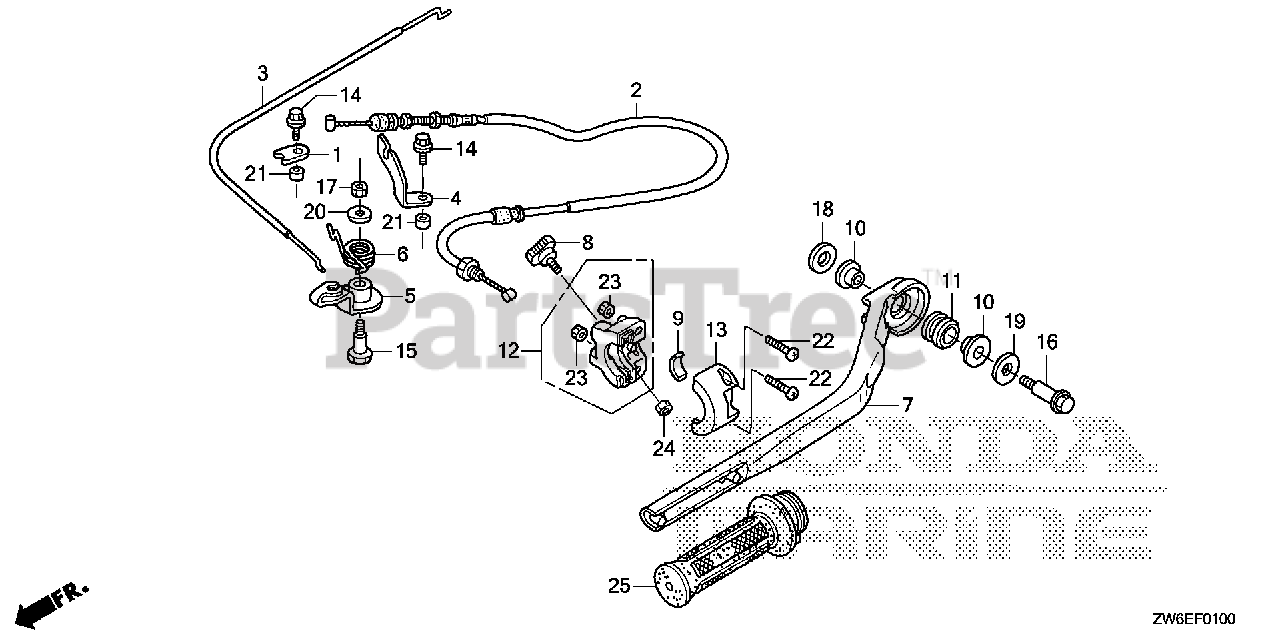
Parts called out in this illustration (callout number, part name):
1	HOLDER, CABLE
2	CABLE A, THROTTLE
2	CABLE, THROTTLE (A)
3	CABLE, THROTTLE (B)
4	HOLDER, CABLE
5	ARM, THROTTLE
6	SPRING, THROTTLE ARM
7	HANDLEBAR *NH246* (LOOSY GRAY)
8	BOLT, FRICTION
9	BLOCK, THROTTLE FRICTION
10	COLLAR, HANDLE MOUNTING
11	RUBBER, HANDLE MOUNTING
12	HOUSING, THROTTLE (LOWER)
13	HOUSING, THROTTLE (UPPER)
14	BOLT, FLANGE (6X12)
15	BOLT, HEX. (6X24)
16	BOLT, SPECIAL (8X42)
17	NUT, HEX. (6MM)
18	WASHER, PLAIN (8MM)
19	WASHER (12.5X32)
20	WASHER, PLAIN (6MM)
21	COLLAR (6.2X8.5X5)
22	SCREW, PAN (5X20)
23	NUT, HEX. (5MM)
24	NUT, HEX. (6MM)
25	GRIP, THROTTLE
